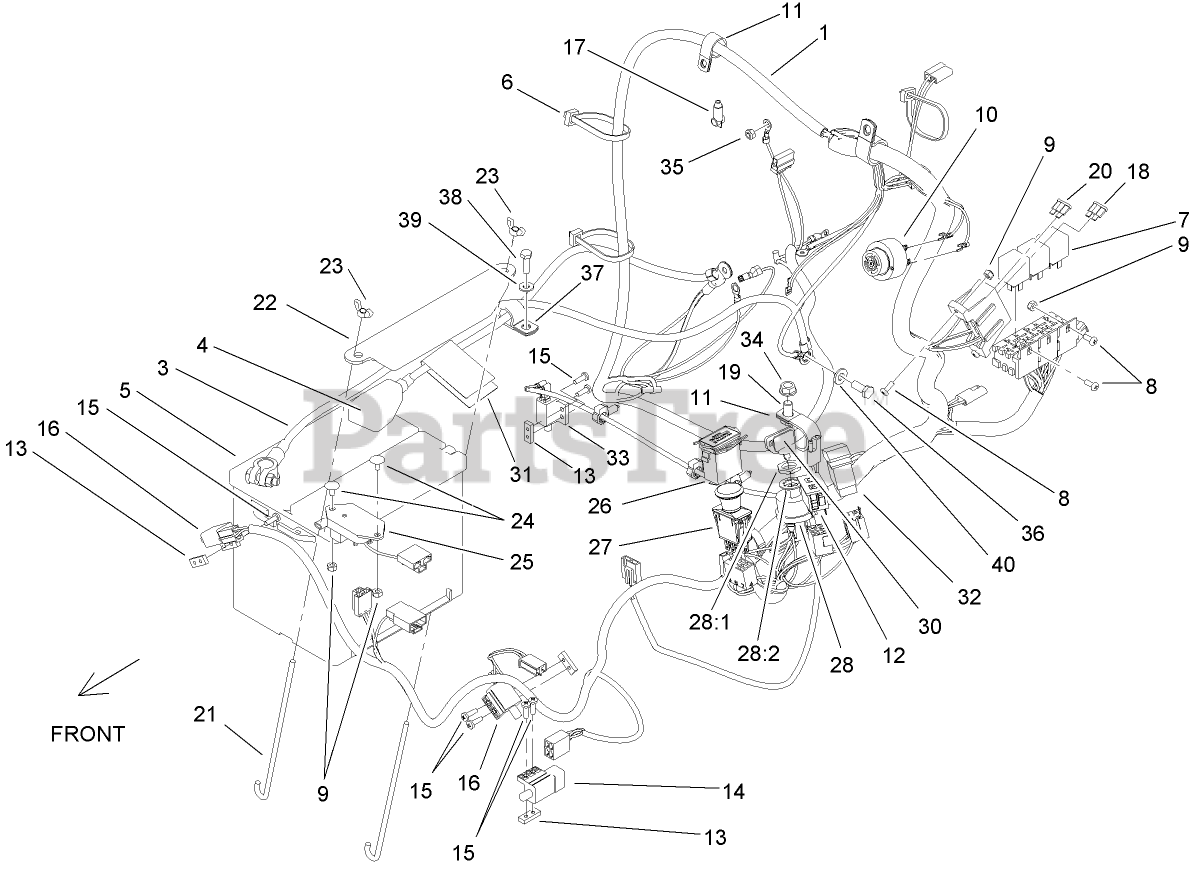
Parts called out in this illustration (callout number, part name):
1	HARNESS-ELECTRICAL, MAIN
3	CABLE-BATTERY, NEGATIVE
4	CABLE-BATTERY, POSITIVE
5	BATTERY-DRY
6	TIE-PLASTIC
9	NUT-LOCK, NI
10	ALARM-TONE, DUAL
11	CLIP-LOOM
12	LAMP-WARNING
13	PLATE-TAPPED
14	SWITCH
15	SCREW-PPH
16	SWITCH-OPEN, NORMALLY
17	CAP-INSULATOR, RED
18	FUSE-40 AMP
19	SCREW-HH
20	FUSE-BLADE, 30 AMP
21	Bolt-Holddown
22	HOLDDOWN-BATTERY
23	WINGNUT
24	BOLT-CARR
25	MODULE-DELAY, SEAT
26	METER-HOUR
27	SWITCH-PTO
28	SWITCH ASM
28:1	NUT-HH
28:2	WASHER-TOOTH, INTERNAL
30	KEY-IGNITION
31	DECAL-INSTRUCTIONS, CHARGING
32	SWITCH-ROCKER
33	SWITCH-CLOSED, NORMALLY
34	NUT-HHF, WHIZ
35	NUT-LOCK
36	SCREW-HH
37	CLIP-LOOM
38	SCREW-HH
39	WASHER-FLAT
40	WASHER-PLAIN
